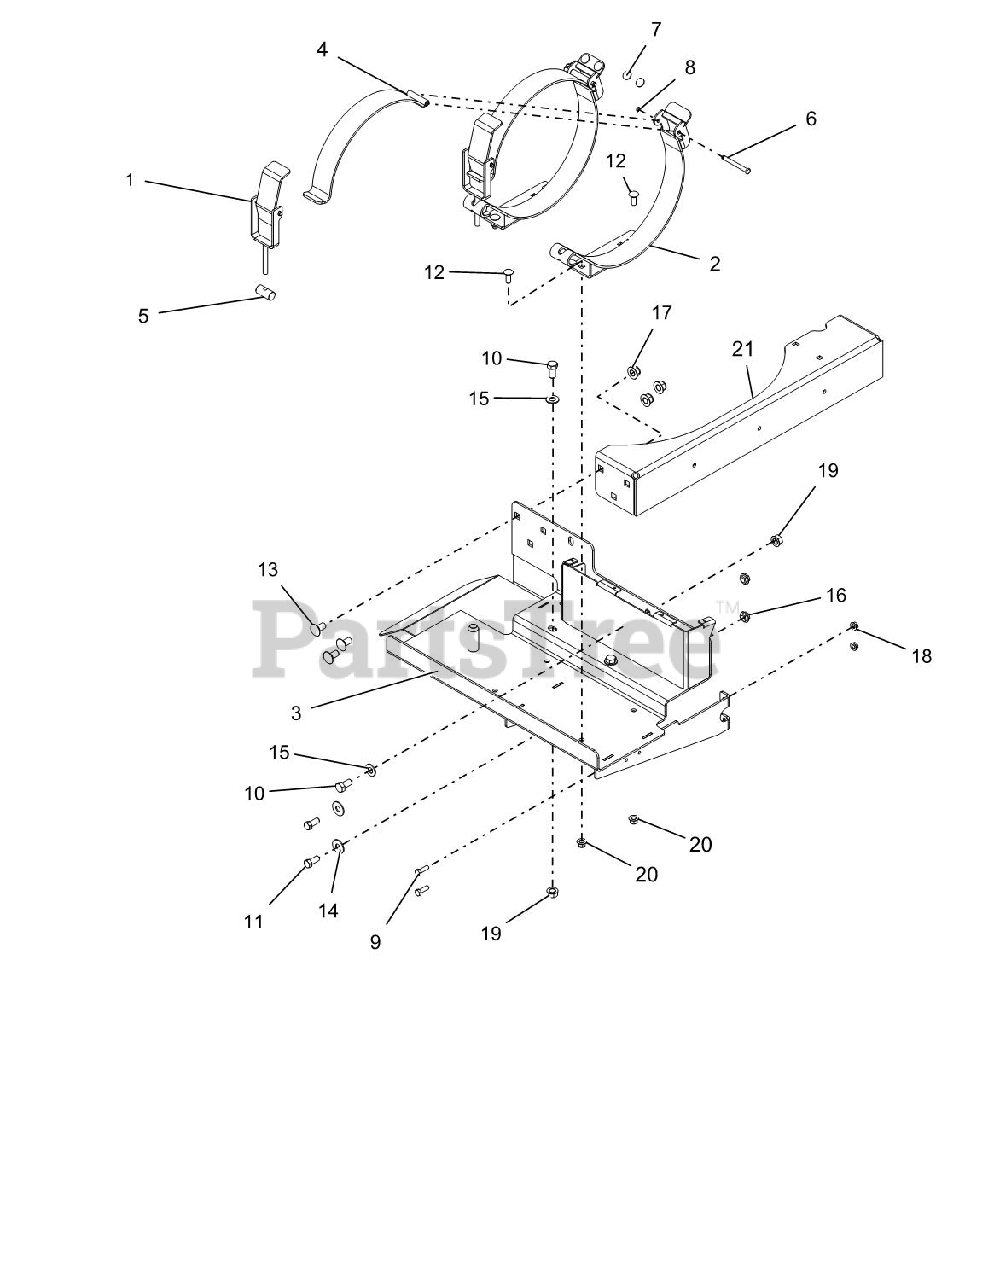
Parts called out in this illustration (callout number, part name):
1	ASM, LP TANK HANDLE CLAMP
2	WLDMT, CLAMP LP TANK-BLACK
3	WLDMT, TANK -LH LP
4	LP TANK CLAMP W/SAFETY DECAL
5	PIVOT, LP CLAMP HANDLE
6	PIN, LP CLAMP
7	MAGNET, .75X.060, LP CLAMP
8	RG-RTNG-EXT .312X.025
9	BLT-HEX .31-18X1.00 GR5 YWZC
10	BLT-HEX .50-13X1.00 GR5 YWZC
11	BLT-HEX .44-14X1.00 GR5 YWZC
12	BLT-RDHDSQNK .38-16X1.00 G5 YWZC
13	BLT-RDHDSQNK .50-13X1.00 G5 Y
14	WSHR-FL-STL..50X1.25X.083 YWZ
15	WSHR-FL-STL.531X1.06X.095YWZC
16	NUT-LK-NYL-FLG .44-14 YWZC
17	NUT-LK-NYL-FLG .50-13 YWZC
18	NUT, LK-TOP-FLG .312-18 YWZC
19	NUT, LK-TOP-FLG .50-13 YWZC
20	NUT-LK-NYL-FLG .38-16 YWZC
21	TANK MNT CROSS SUPPORT W/SAFETY DECAL
